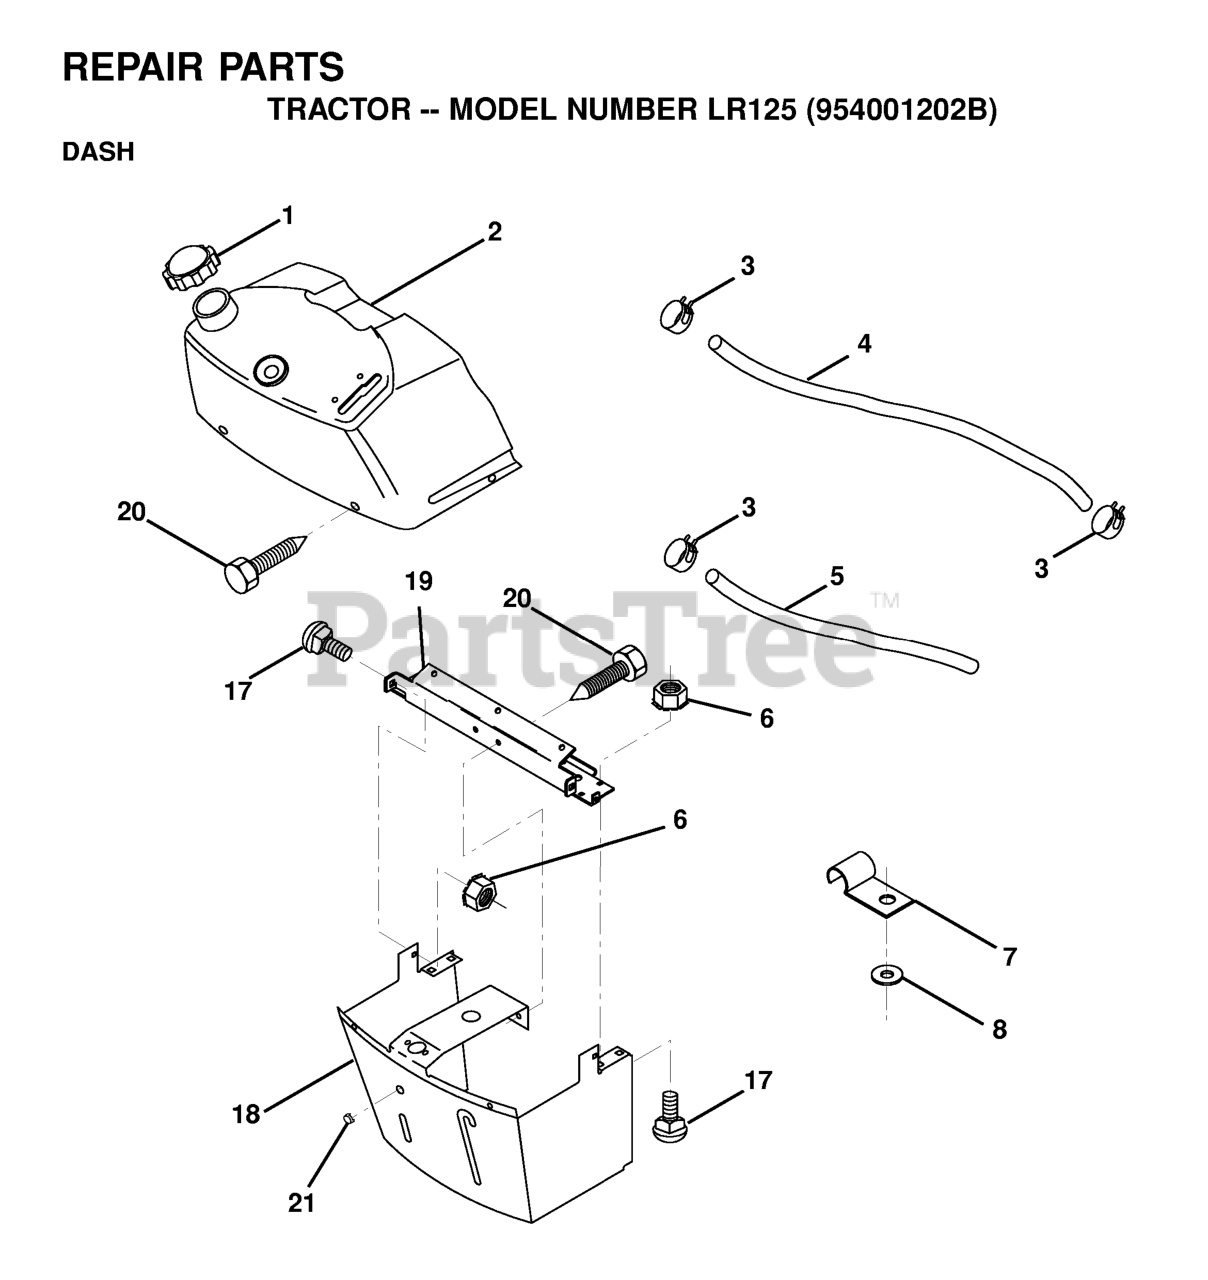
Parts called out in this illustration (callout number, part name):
1	CAP.FUEL.GREY
2	TANK ASM DASH LR
3	HOSE CLAMP
4	FUEL LINE
5	FUEL LINE T
6	Nut, Keps Blk Hex 1/4-20 UNC
7	CLIP T
18	SUPT ASM DASH
19	CROSS BRACE
